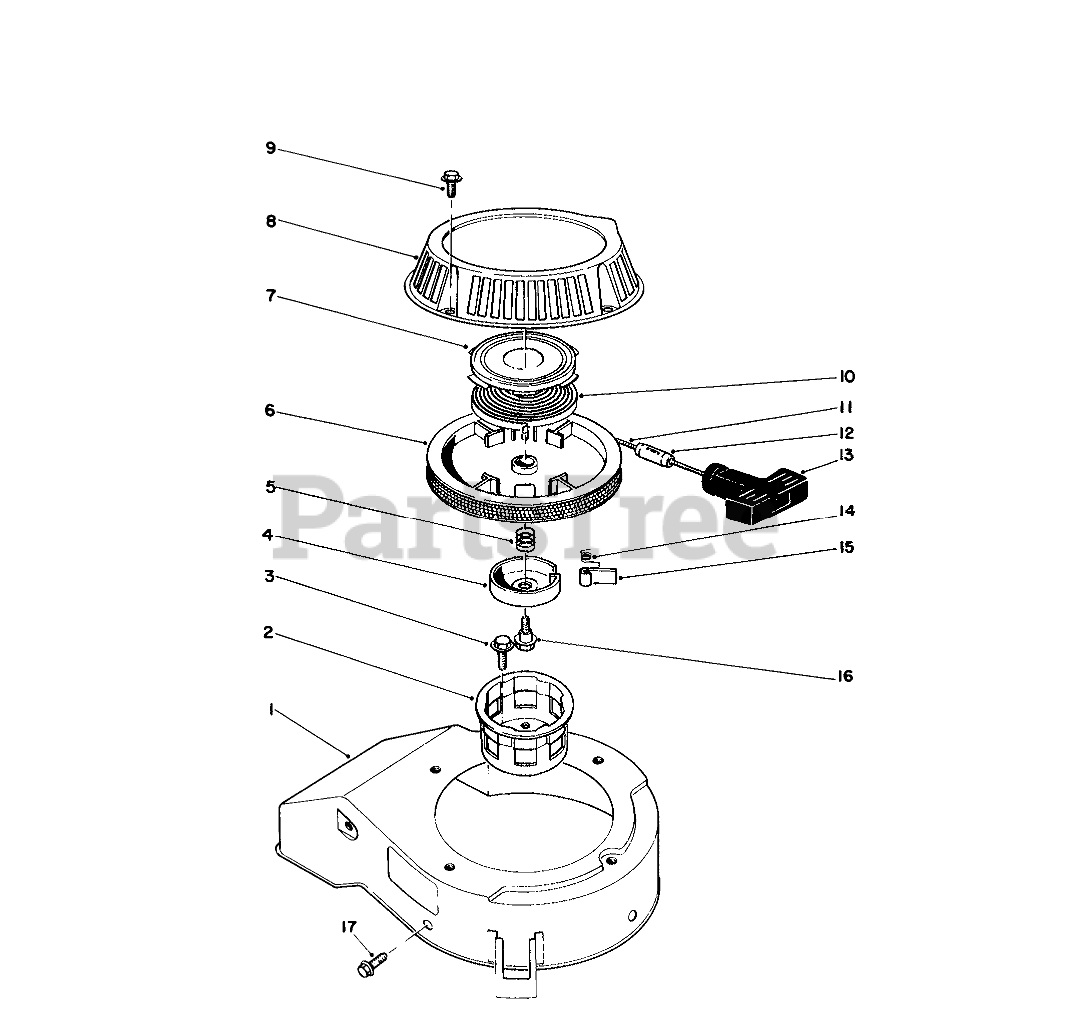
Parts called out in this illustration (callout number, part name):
1	COVER
2	CUP - STARTER
4	RETAINER
5	SPRING
7	Retainer Cup-Recoil Spring
9	SCREW-HHF
10	Spring-Recoil
11	ROPE-STARTER
13	HANDLE-RECOIL
14	SPRING
